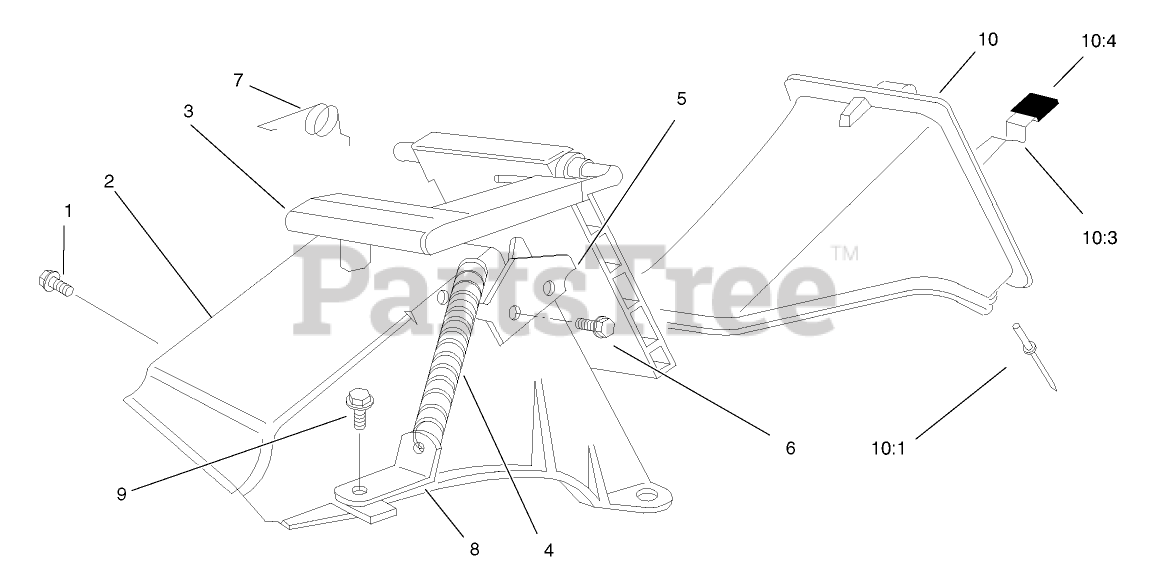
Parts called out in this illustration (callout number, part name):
1	SCREW AND WASHER ASM
2	TUNNEL-DISCHARGE
3	DISCHARGE DOOR ASM
4	SPRING-DOOR
5	LATCH-PLATE
6	SCREW-PLASTITE
7	RETAINER-DOOR
8	BRACKET-SPRING
9	SCREW-HWH
10	DISCHARGE PLUG ASM
10:1	RIVET-HEAD, FLAT
10:3	LATCH-PLUG, DISCHARGE
10:4	GRIP-LATCH
